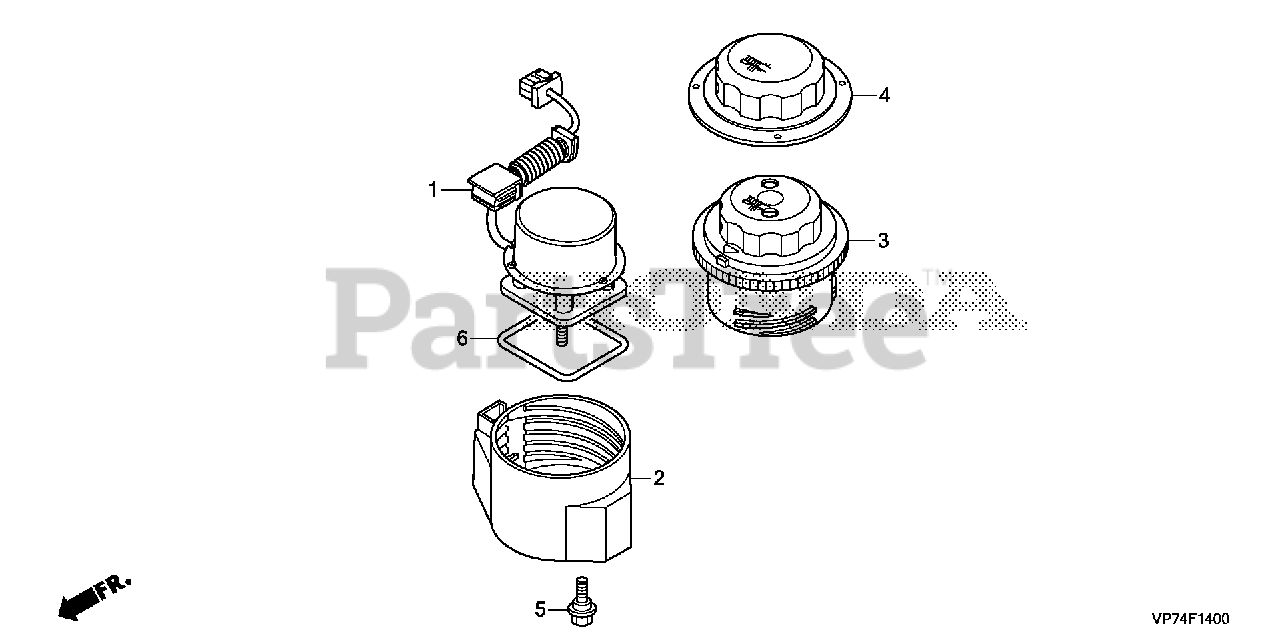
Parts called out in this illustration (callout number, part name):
1	MOTOR ASSY., WORK
2	HOUSING, MOTOR
3	HANDLE, HEIGHT ADJUSTER
5	BOLT, SPECIAL (6MM)
6	O-RING, MOTOR MOUNT
